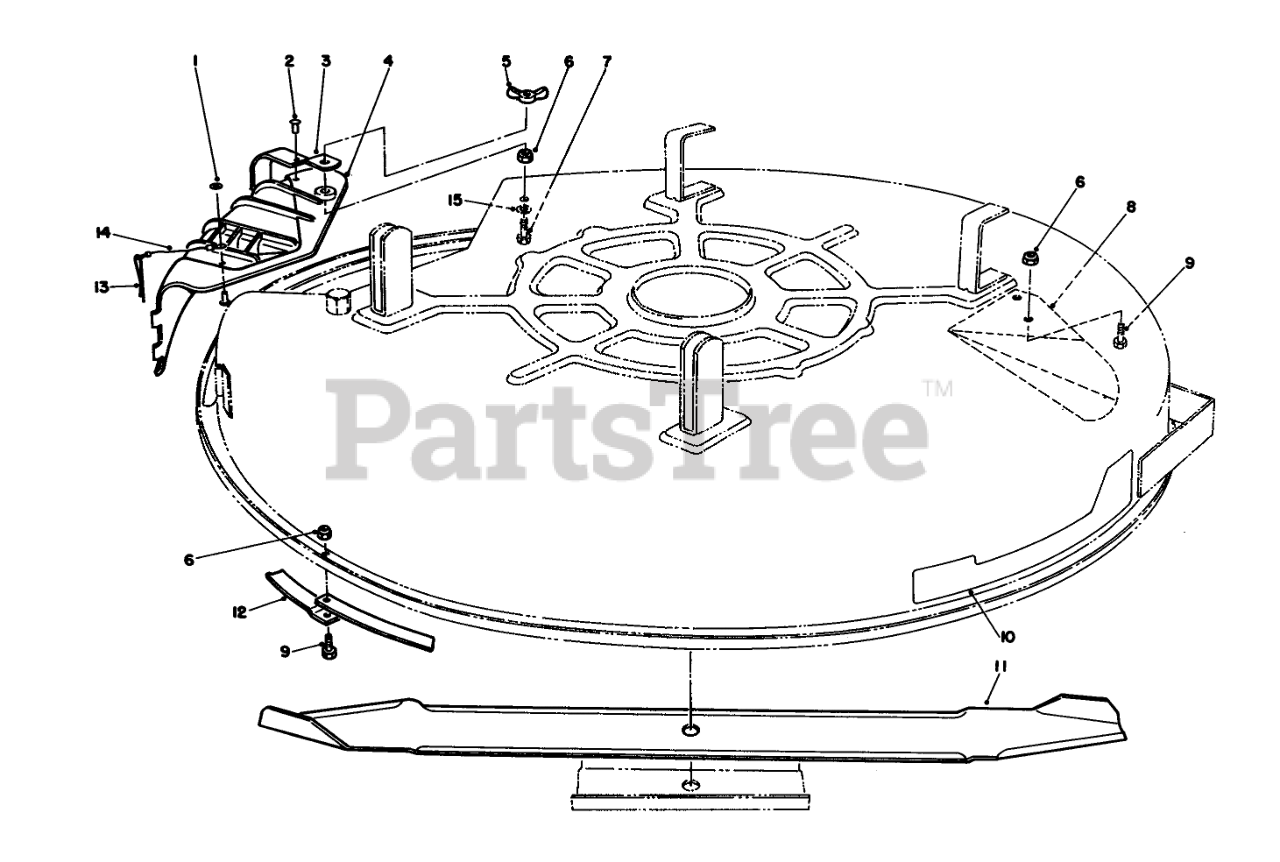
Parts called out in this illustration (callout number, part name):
1	WASHER-PLAIN
2	RIVET-BLIND
3	Brace-Cover, Rear
4	Assy.-Cover, Discharge (Incl. Ref. #1, 2, 13 & 14)
5	NUT-WING
6	NUT-LOCK, NI
7	SCREW-HH
8	Kicker
9	SCREW-HH
10	DECAL/RECYCLER 32" BACK
11	BLADE-RECYCLER
12	RING-DECK
13	PIN-LOCKING, CHUTE
14	LANYARD
15	WASHER-PLAIN
